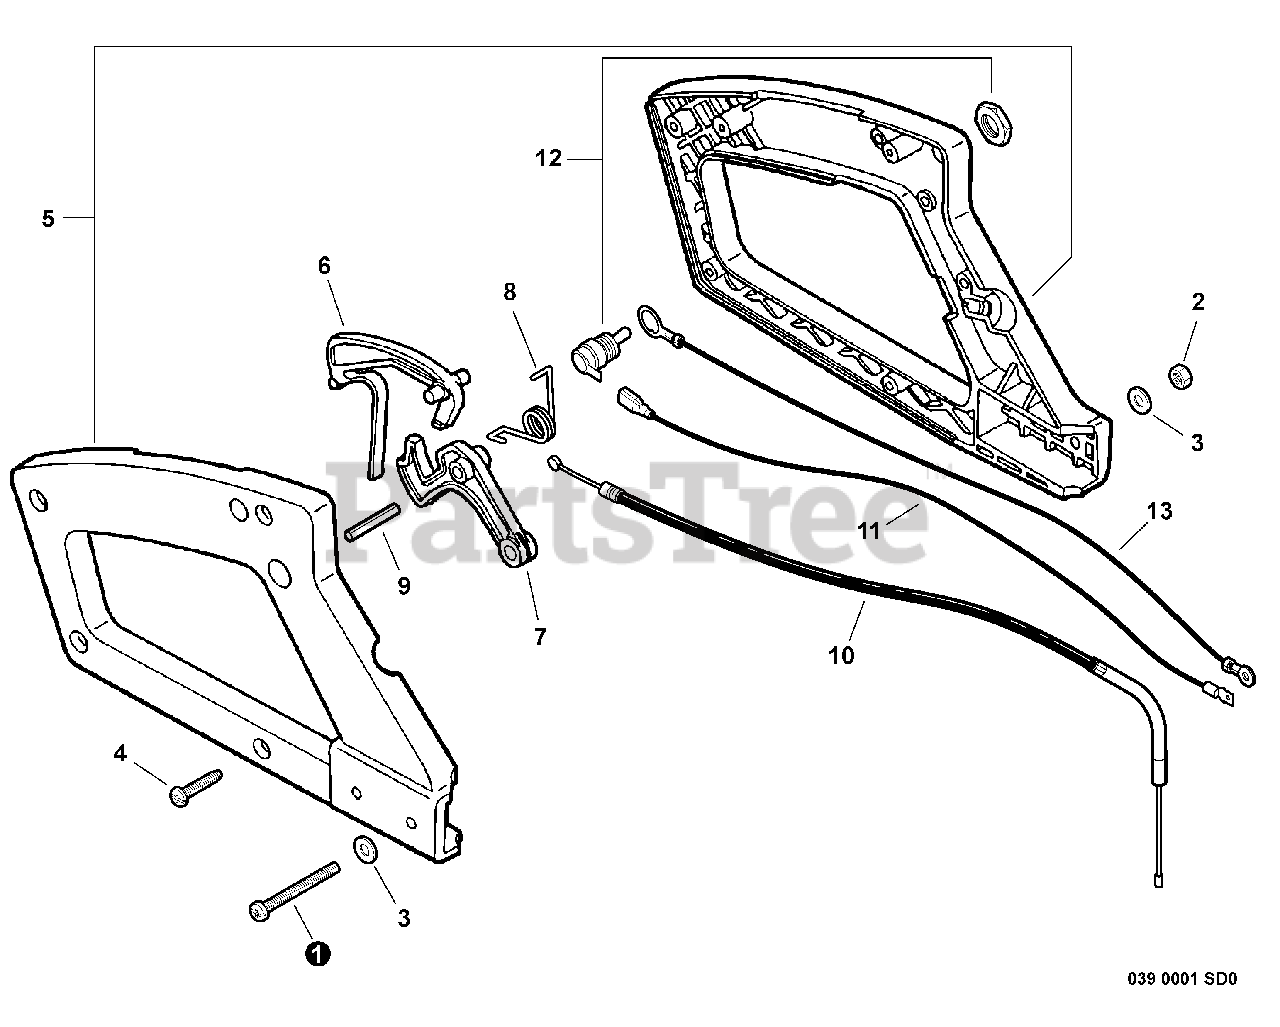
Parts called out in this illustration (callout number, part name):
1	SCREW - 5X40
2	LOCKNUT - 5
3	WASHER - 5
4	SCREW - 4X16
5	HANDLE ASSY - REAR
6	LEVER, TRIGGER LOCKOUT
7	TRIGGER, THROTTLE
8	SPRING, TRIGGER
9	PIN - SPRING -- 5X25
10	CABLE, THROTTLE
11	LEAD - IGNITION
12	IGNITION SWITCH ASSY
13	LEAD - GROUND
